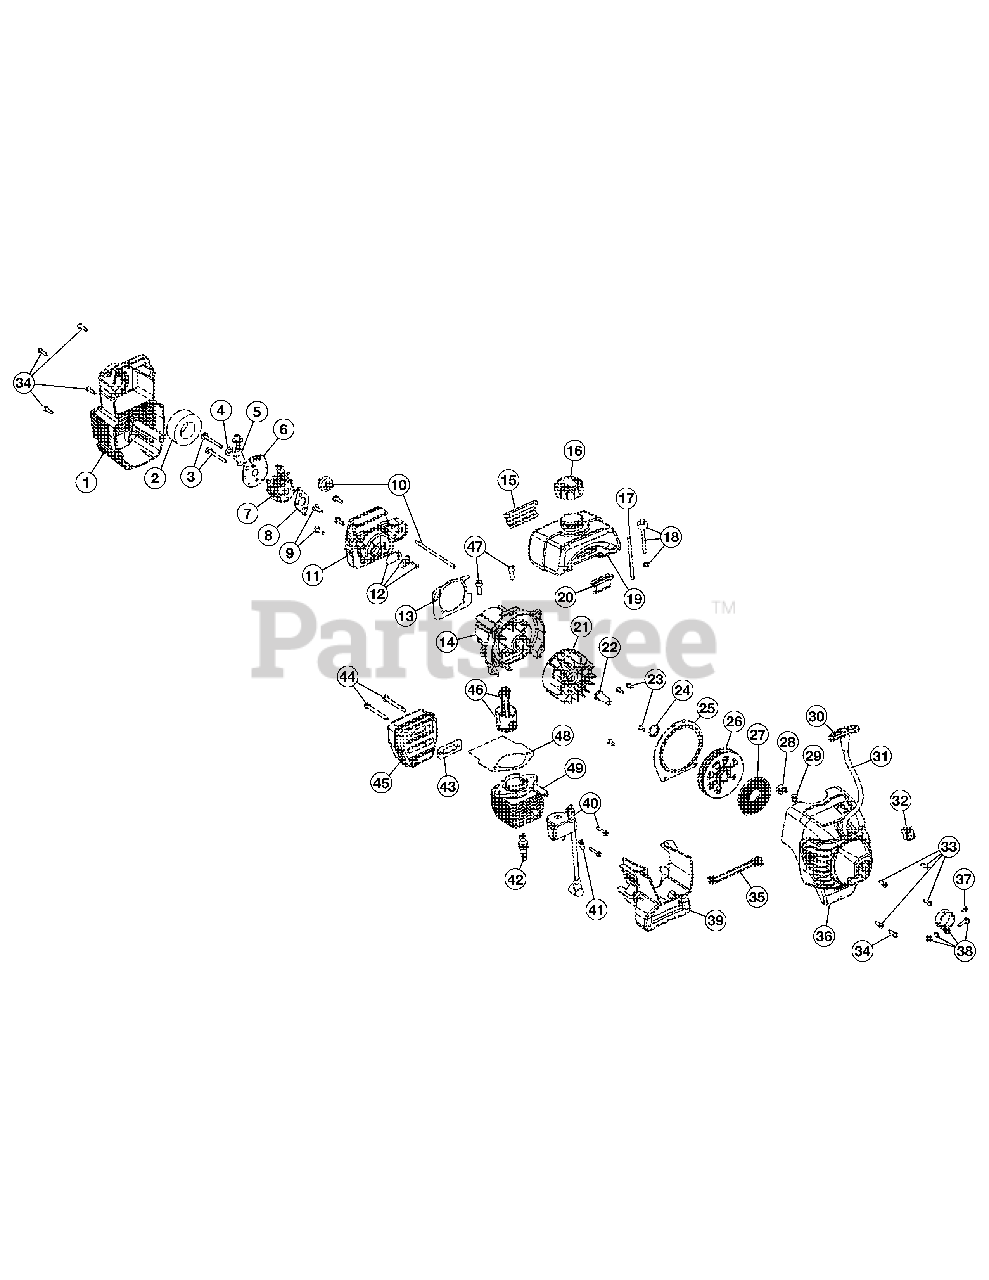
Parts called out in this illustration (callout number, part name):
1	Air Cleaner Cover Assembly (includes 2 & 34)
2	Air Cleaner Filter
3	Carburetor Mounting Screws
4	Wavey Washer
5	Choke Lever Assembly
6	Choke Lever & Plate (includes 5)
7	Carburetor Assembly (includes 8 & 18)
8	Carburetor Gasket
9	Carb Mount Screw
10	Primer and Hose Assembly
11	Carburetor Mount Assembly (includes 9, 12 & 13)
12	Reed Assembly
13	Carburetor Mount Gasket
14	Crankcase Service Assembly (includes 9)
15	Rear Mounting Pad
16	Fuel Cap Assembly
17	Fuel Return Line
18	Fuel Line Assembly
19	Fuel Tank Assembly (includes 16-18)
20	Front Mounting Pad
21	Flywheel Assembly
22	Square Nut Drive
23	Plate Screw
24	Palnut
25	Pressure Plate (includes 23 & 28)
26	Recoil Pulley Assembly (includes 24)
27	Recoil Spring
28	Eyelet Retainer
29	Rope Guide
30	Pull Handle
32	Switch Assembly
33	Housing Screw
34	Cover Screw
35	Wire Lead
36	Starter Housing Assembly (includes 23-35)
37	Anti-Rotation Screw
38	Clamp Assembly (includes 37)
39	Shroud Extension and Stand (includes 34)
40	Module Assembly
41	Ground Tab
42	Spark Plug
43	Exhaust Gasket
44	Muffler Mounting Bolt Assembly
45	Muffler Assembly (includes 43, 44 & Spark Arrestor)
46	Piston & Rod Assembly
47	Cylinder Bolt
48	Cylinder Gasket
